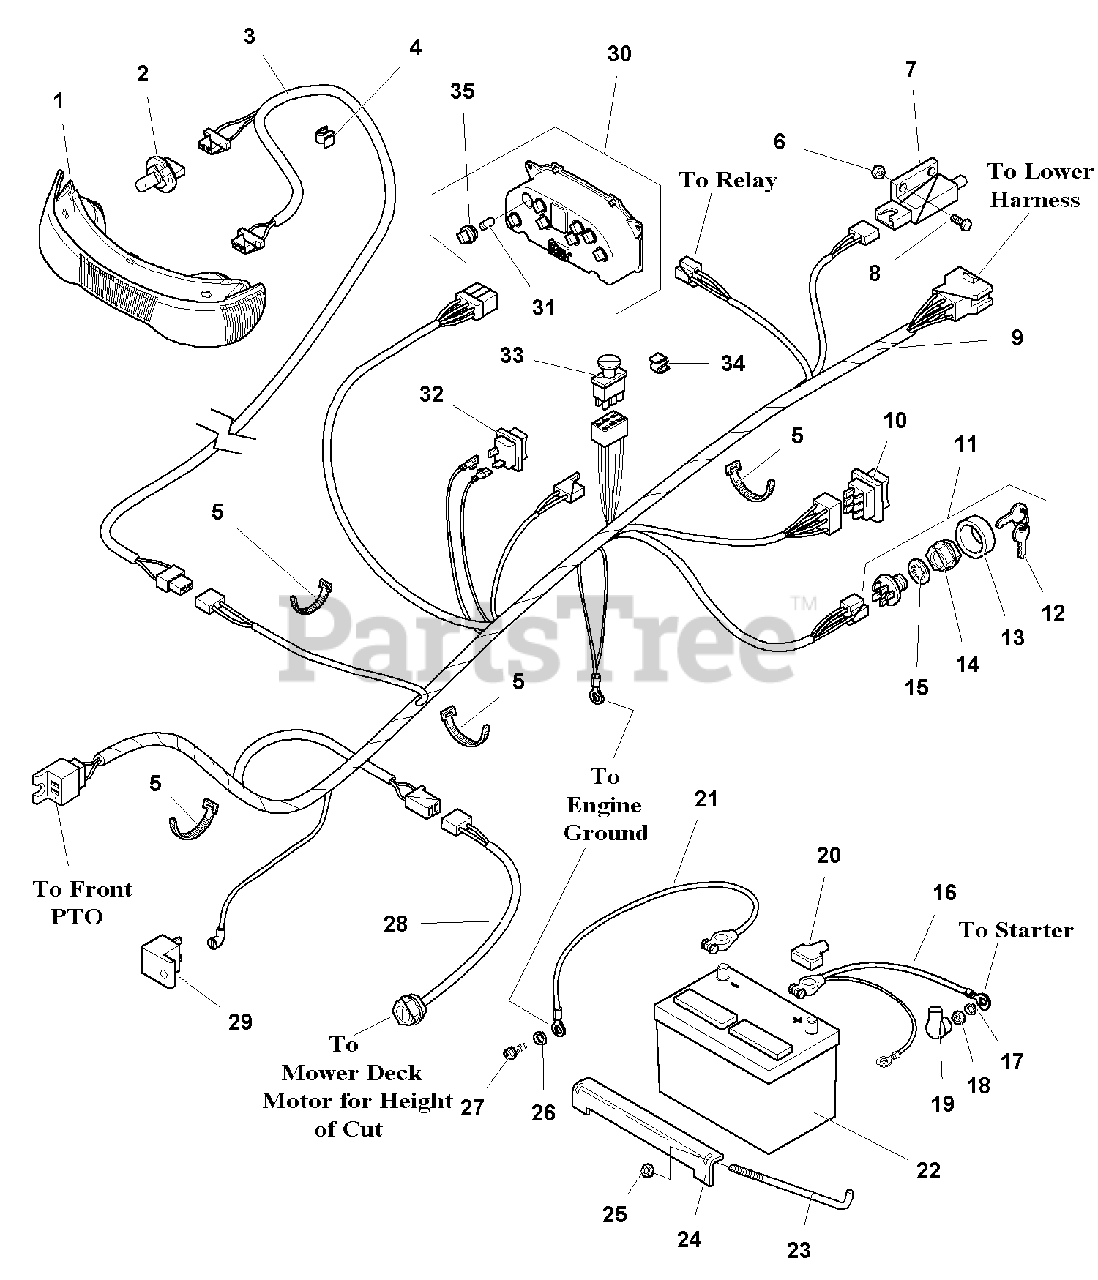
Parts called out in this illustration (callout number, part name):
1	BEZEL, Headlight
2	BULB, Headlight, Halogen
3	HARNESS, Headlight
6	NUT, KEPS Lock, #10-24
7	SWITCH, Interlock (NO/NO), Brake Pedal
8	CAPSCREW, #10-24 x 5/8
9	HARNESS, Main
10	SWITCH, Mower Height Adjust
11	ASSEMBLY, Switch & Key (Includes Ref. Nos. 12 -15)
12	KEYS (Set of 2)
13	COVER, Key Switch
14	NUT, Hex Flange, 5/8
15	WASHER, Internal Tooth, 5/8
16	CABLE, Battery to Starter
17	LOCKWASHER, 5/16
18	NUT, Hex Jam, M8-1.25, Yellow
19	COVER, Starter Terminal
20	COVER, Positive Battery Terminal
21	CABLE, Battery to Ground
22	BATTERY (500 CCA)
23	ROD, Battery Hold Down
24	BRACKET, Battery
25	NUT, Hex, Nylon Lock, 1/4-20
26	LOCKWASHER, 3/8
27	CAPSCREW, 3/8-16 x 5/8
28	HARNESS, Power Outlet
29	BREAKER, Circuit
30	PANEL, Instrument (Includes Bulbs & Bulb Holders)
31	BULB, Instrument Panel
32	SWITCH, Headlights
33	SWITCH, Front P.T.O.
35	HOLDER, Bulb
